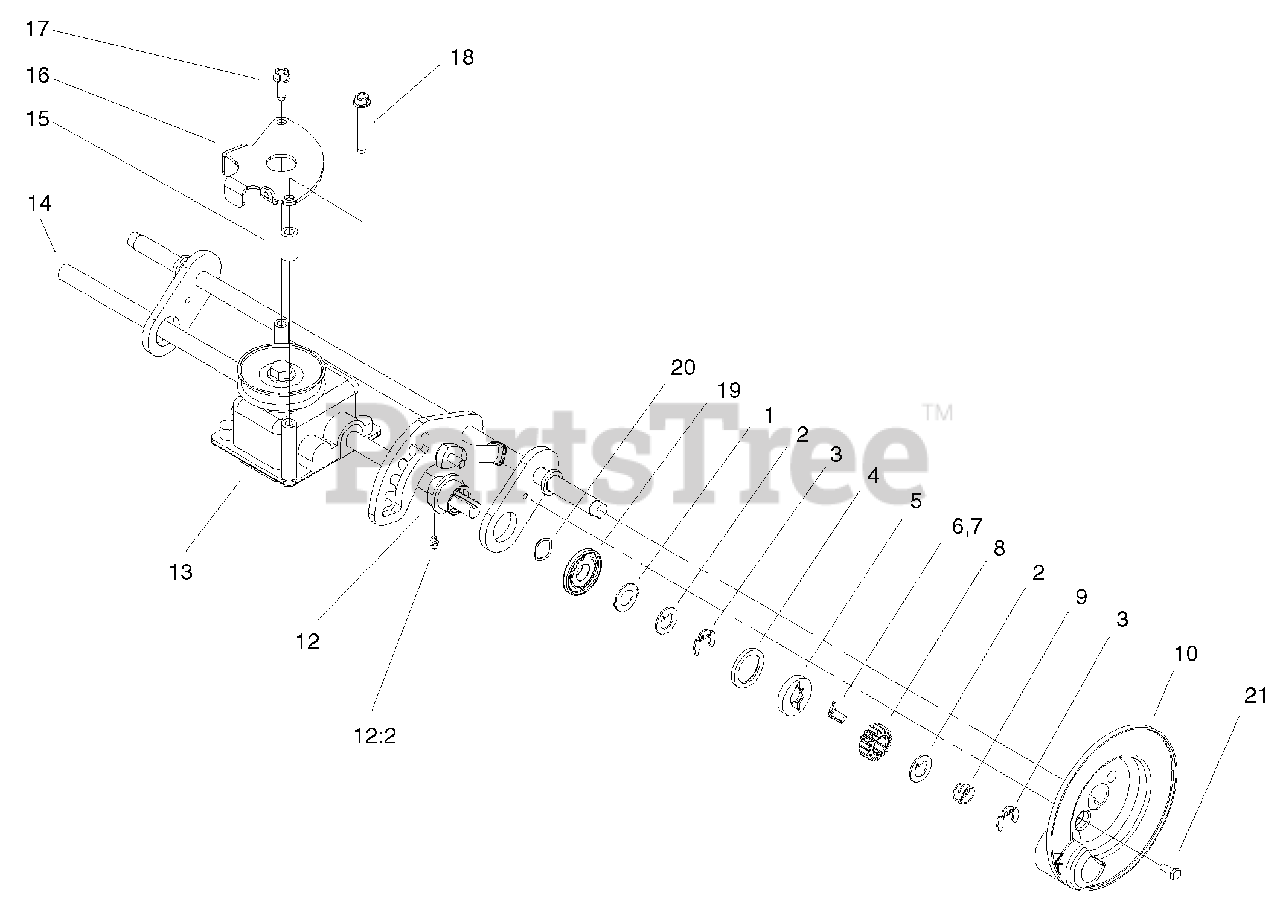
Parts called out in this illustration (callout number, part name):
1	Washer-Arm, Pivot (only on: 10926)
2	Washer-Thrust, Keyed (only on: 10926)
3	Ring-Klip (only on: 10925)
3	Ring-Klip (only on: 10926)
4	Ring-Friction (only on: 10926)
5	Washer-Clutch (only on: 10926)
6	Key-Rocking, RH (only on: 10926)
7	Key-Rocking, LH (only on: 10926)
8	Gear-Pinion (only on: 10926)
9	Spring-Compression (only on: 10926)
10	Cover-Gear
12	Bushing-Zerk ASM
12:2	Fitting-Zerk
13	Transmission ASM (only on: 10926)
14	Shaft-Pivot (only on: 10925)
15	Bushing-Plate, Actuator (only on: 10926)
16	Guide-Transmission (only on: 10926)
17	Screw-Taptite (only on: 10926)
18	Screw-HWHTF (only on: 10926)
19	Retainer-Ring (only on: 10926)
20	Washer-Wave (only on: 10926)
21	Screw-Taptite
